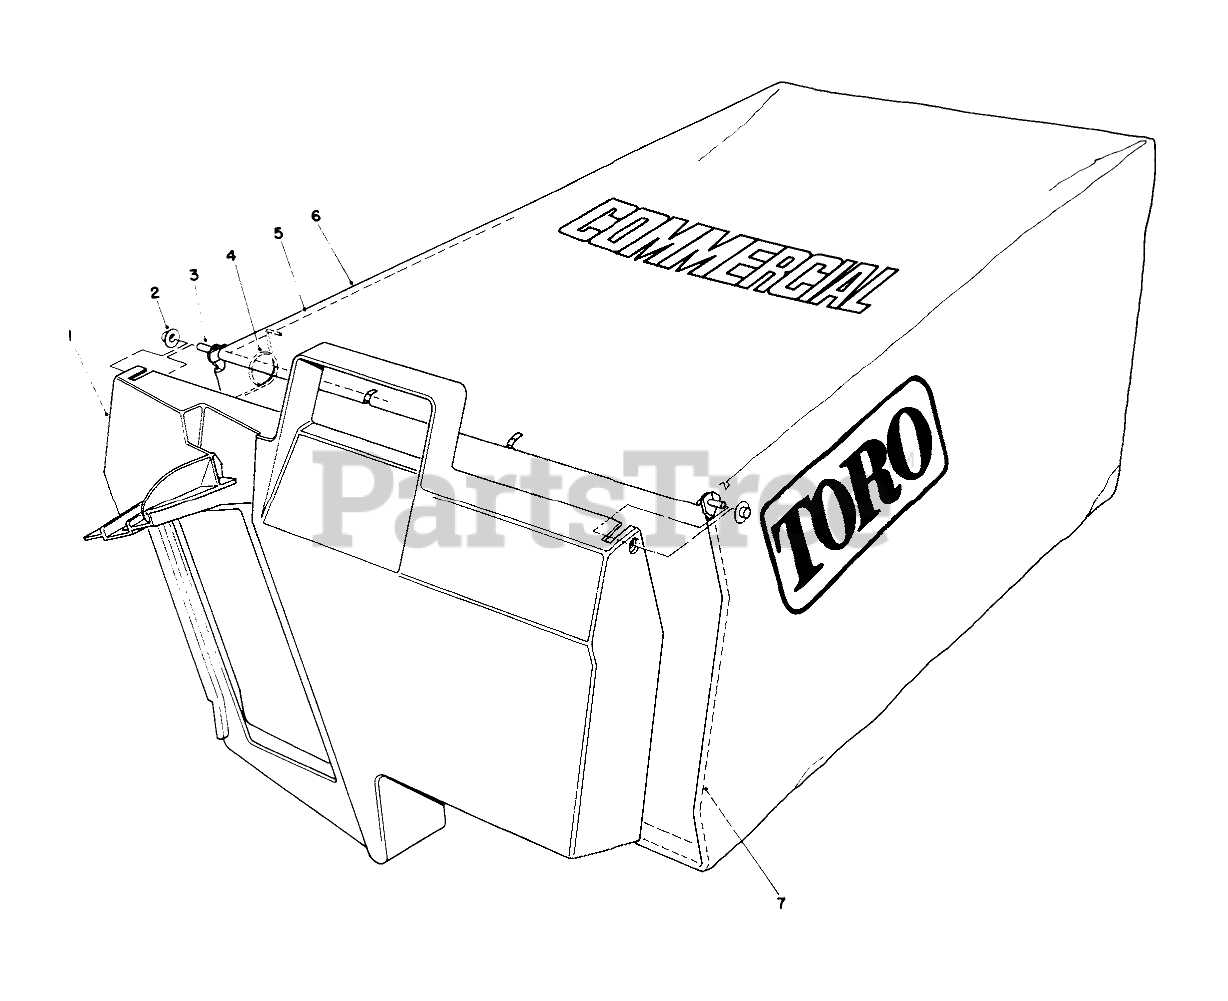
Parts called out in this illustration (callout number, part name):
1	DOOR-BAG, GRASS
2	NUT-PUSH
3	HINGE-DOOR, BAG
4	SPRING
5	FRAME-BAG, UPPER
6	Bag
7	FRAME-BAG
